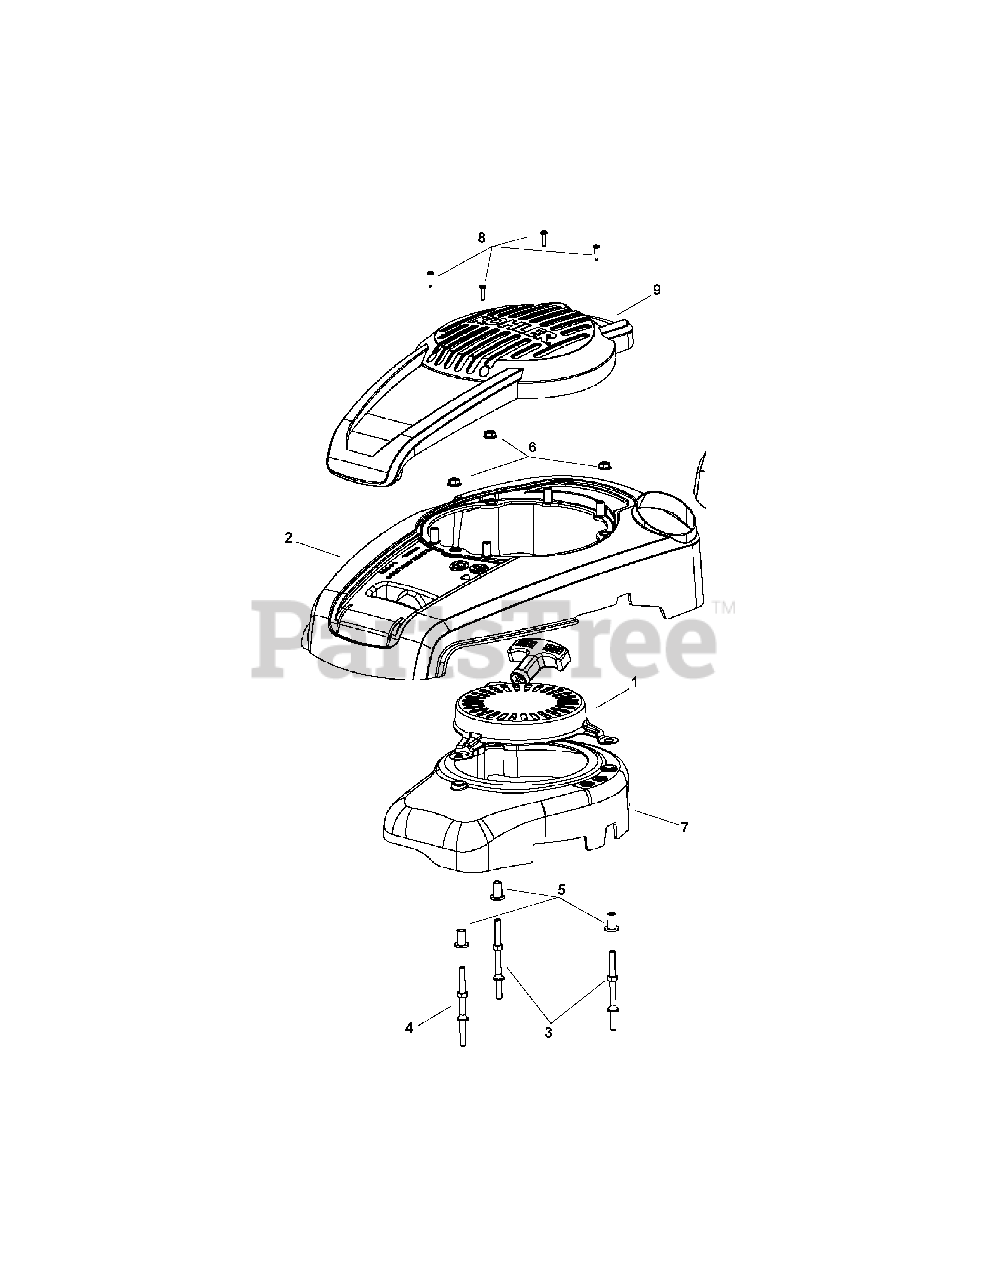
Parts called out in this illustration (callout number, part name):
1	Retractable Starter Assembly
2	Engine Cover, Black
3	Stud
4	Stud
6	Hex Flange Nut, M6
7	Blower Housing
8	Screw, #15 6-Lobe Pan Hd
9	Engine Cover Insert, Black
